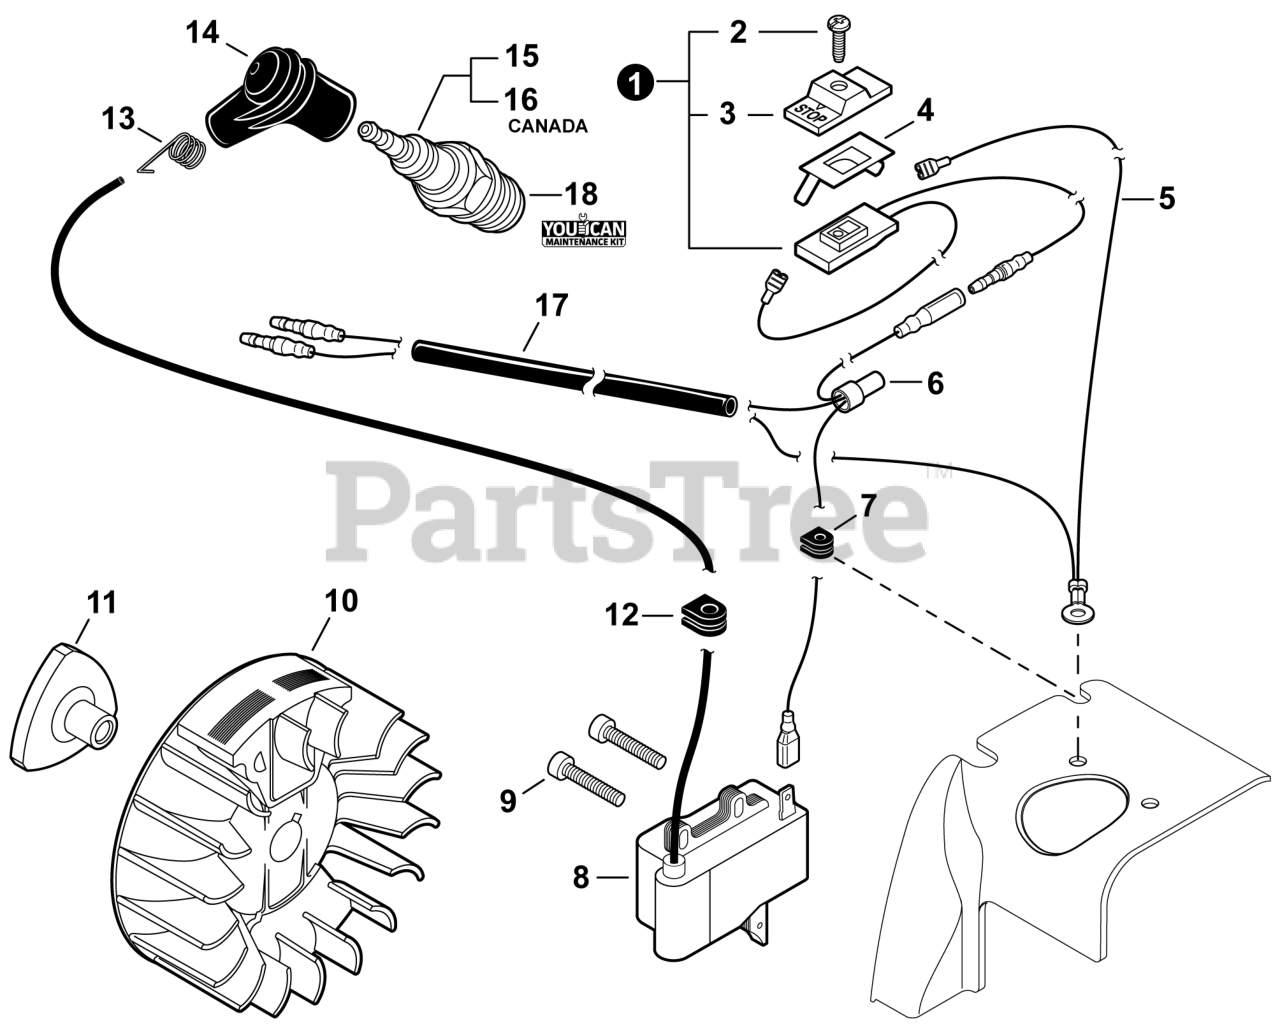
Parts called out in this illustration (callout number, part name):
1	SWITCH ASSY, ON-OFF
2	SCREW 3x10
3	KNOB, SWITCH
4	TERMINAL, LEAD
8	COIL, IGNITION
9	BOLT, TORX 4x20
10	FLYWHEEL
11	HUB, FAN
13	TERMINAL, SPARK PLUG
14	CAP, SPARK PLUG
15	SPARK PLUG - BPM8Y
16	SPARK PLUG - BPMR8Y
17	TUBE, INSULATOR
18	TUNE-UP KIT - YOUCANT
